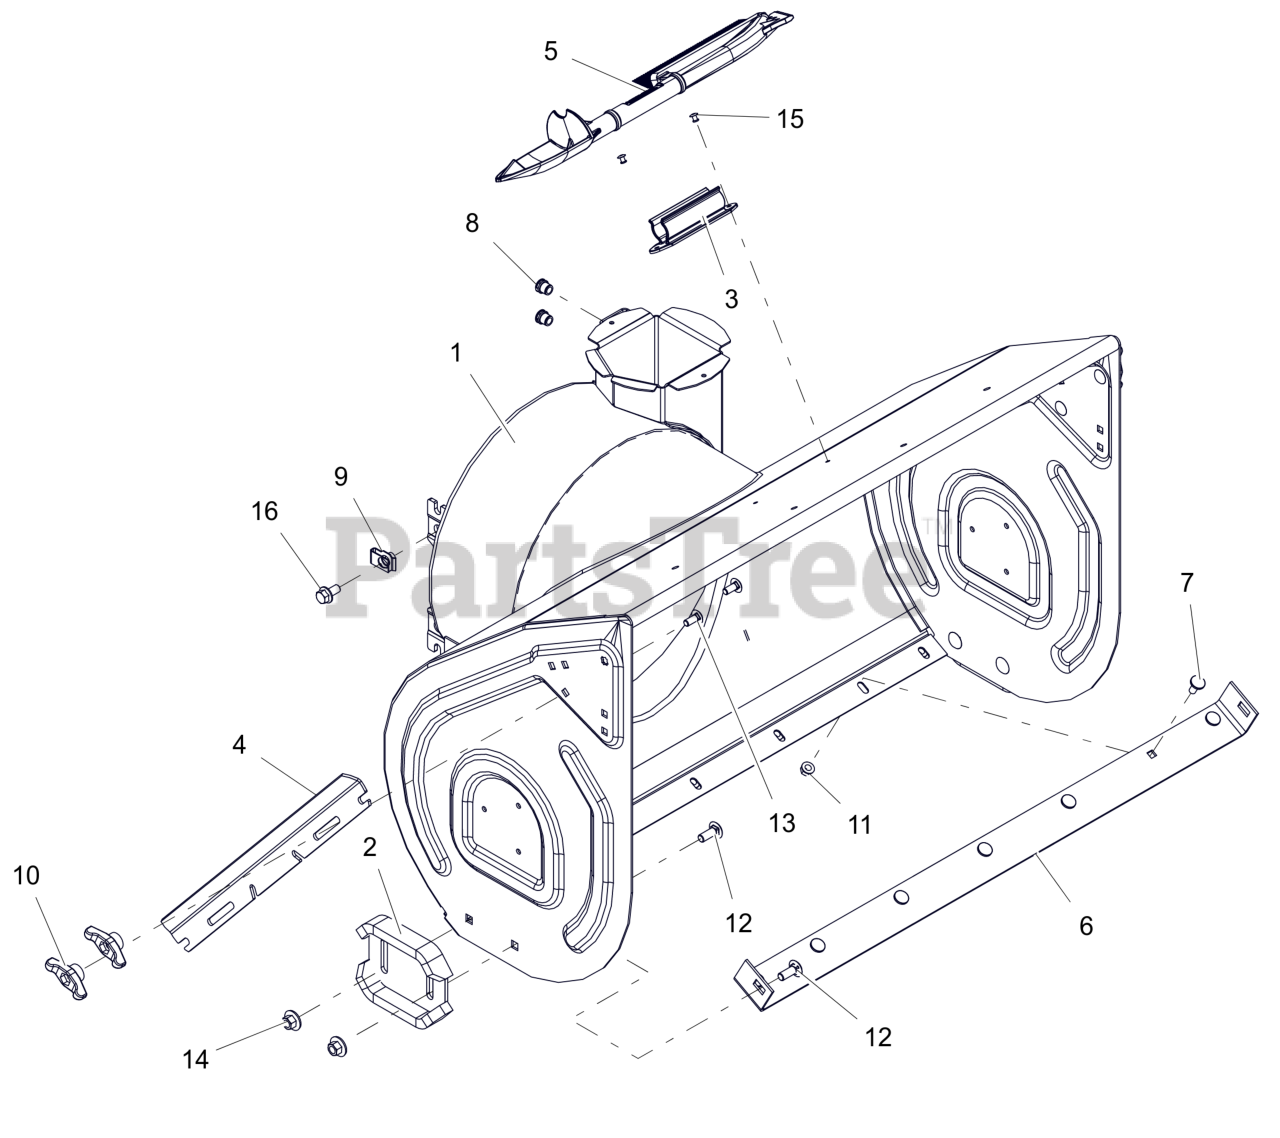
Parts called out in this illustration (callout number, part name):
1	HOUSING, PRO W/DECAL 32"
2	RUNNER, SKID SHOE
3	MOUNT, SNOW CLEAN OUT
4	CUTTER, DRIFT
5	DEVICE, SNOW CLEAN OUT W/BRUSH
6	BLADE, SCRAPER-32"
7	BOLT, MODIFIED HEAD CARRIAGE
8	NUT,THD,INSERT .38-16 ZC120
9	NUT-RTNR .375-16X.37
10	KNOB,WING .31-18 UNC NYL/TALC
11	NUT-LK-TOP-FLG .312-18 GF ZCC
12	BLT,RHSSN .38-16X1.00 G5 ZCC
13	BLT, RHSSN.31-18X.750 G5 ZCC
14	NUT- CON-LN .375-16 ZC120
15	RVT, POP .1875 ZCC
